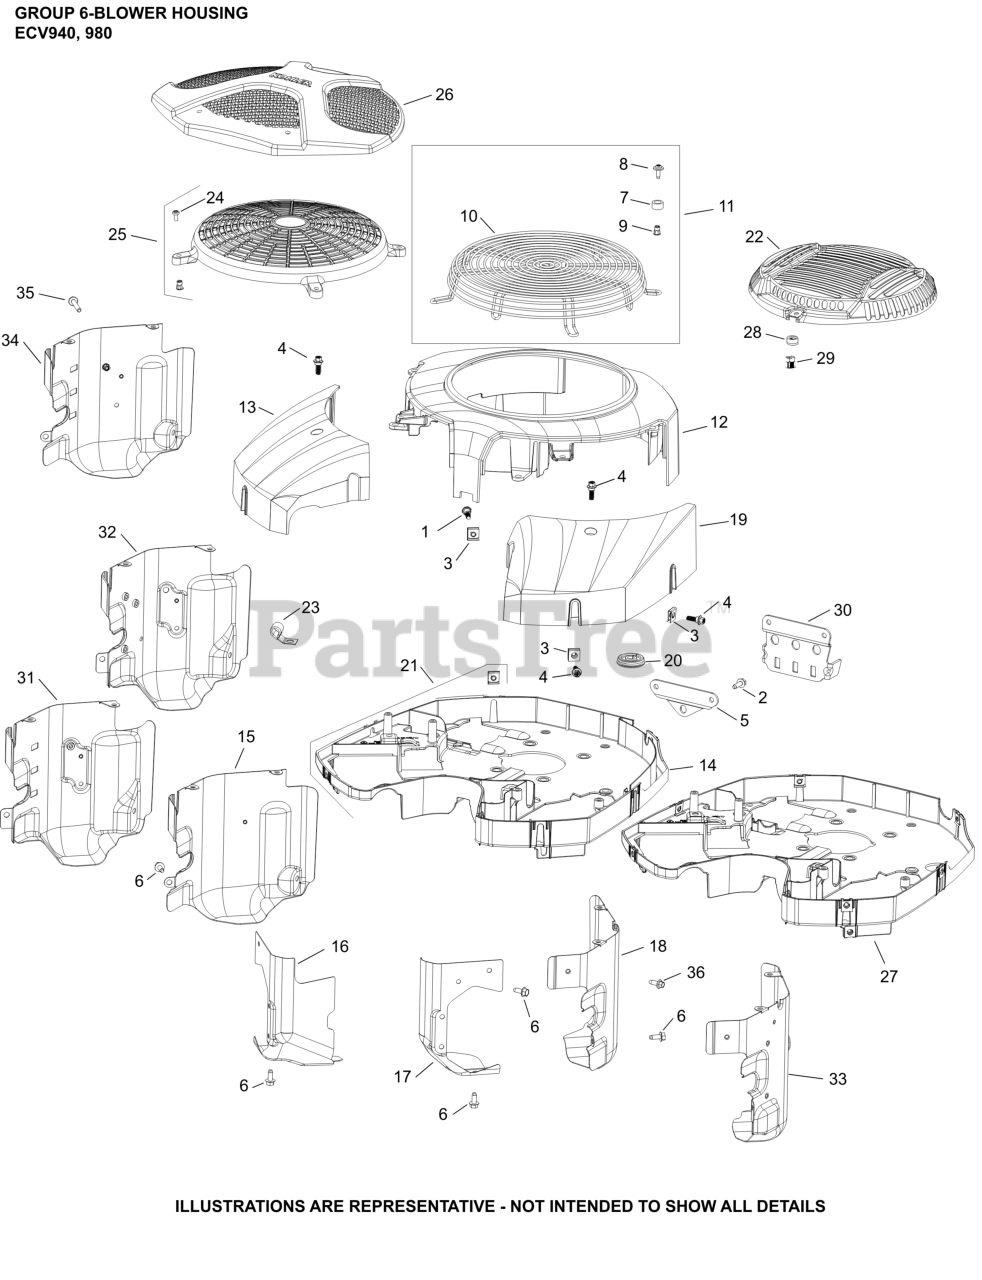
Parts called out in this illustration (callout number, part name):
1	SCREW, SHD THD FRM M6X1X26
2	SCREW, THREAD FORMING
3	CLIP, BAFFLE MOUNTING
4	SCREW, SHD THD FRM
5	STRAP, LIFTING
6	SCREW, THREAD FORMING
8	SCREW, SEMS
12	KIT, BLOWER HOUSING
13	SHROUD, #1 CYLINDER
16	BAFFLE, VALLEY #1 CYLINDER
17	BAFFLE, VALLEY #2 CYL-USE 62 063 40-S
18	BAFFLE, BARREL (#2 CYL)
19	SHROUD, #2 CYLINDER
20	CGROMMET, WIRING HARNESS
22	GUARD, GRASS SCREEN (METAL)
27	SHROUD AND CLIP ASSEMBLY
29	INSERT, THREADED (M5)
35	SCREW, HEX FLANGE
36	SCREW, THREAD FORMING
NI	BAFFLE, BARREL (#1 CYL)
